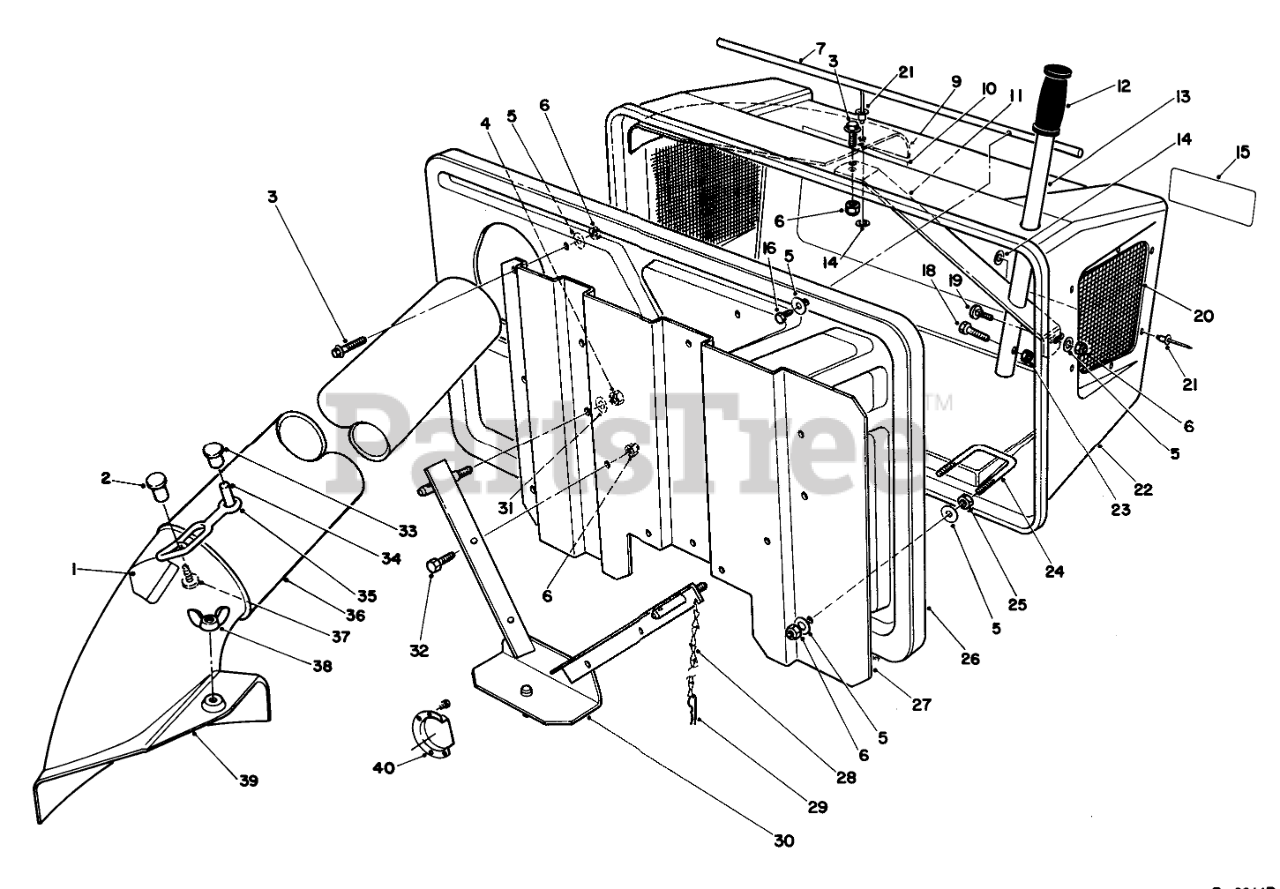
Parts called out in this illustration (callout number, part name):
1	DECAL-DANGER
3	SCREW-HHF
4	NUT-LOCK, NI
5	WASHER-FLAT
6	NUT-LOCK, NI
7	PIVOT ROD
9	DEFLECTOR
10	DECAL
11	HANDLE GUIDE
13	HANDLE TUBE
14	WASHER-FLAT
15	EASY EMPTY BAG DECAL
16	SCREW-HH
18	SCREW-HH
19	BOLT-CARR
20	SCREEN
21	RIVET-POP
22	HOPPER
23	NUT-HEX, SIDE DEFORM
24	LATCH
25	NUT-HEX
27	Plate-Mounting
28	6-LINK CHAIN W/HOOK
29	PIN-HAIR
30	V-Bracket
31	WASHER-FLAT
32	SCREW-HH
33	FASTENER-PANEL
34	SPACER-INTERLOCK
35	RETAINER-DUCT
37	Screw
38	NUT-WING SPECL
39	Chute (Incl. Ref. #1, 2 & 37)
40	MUFFLER DEFLECTOR
